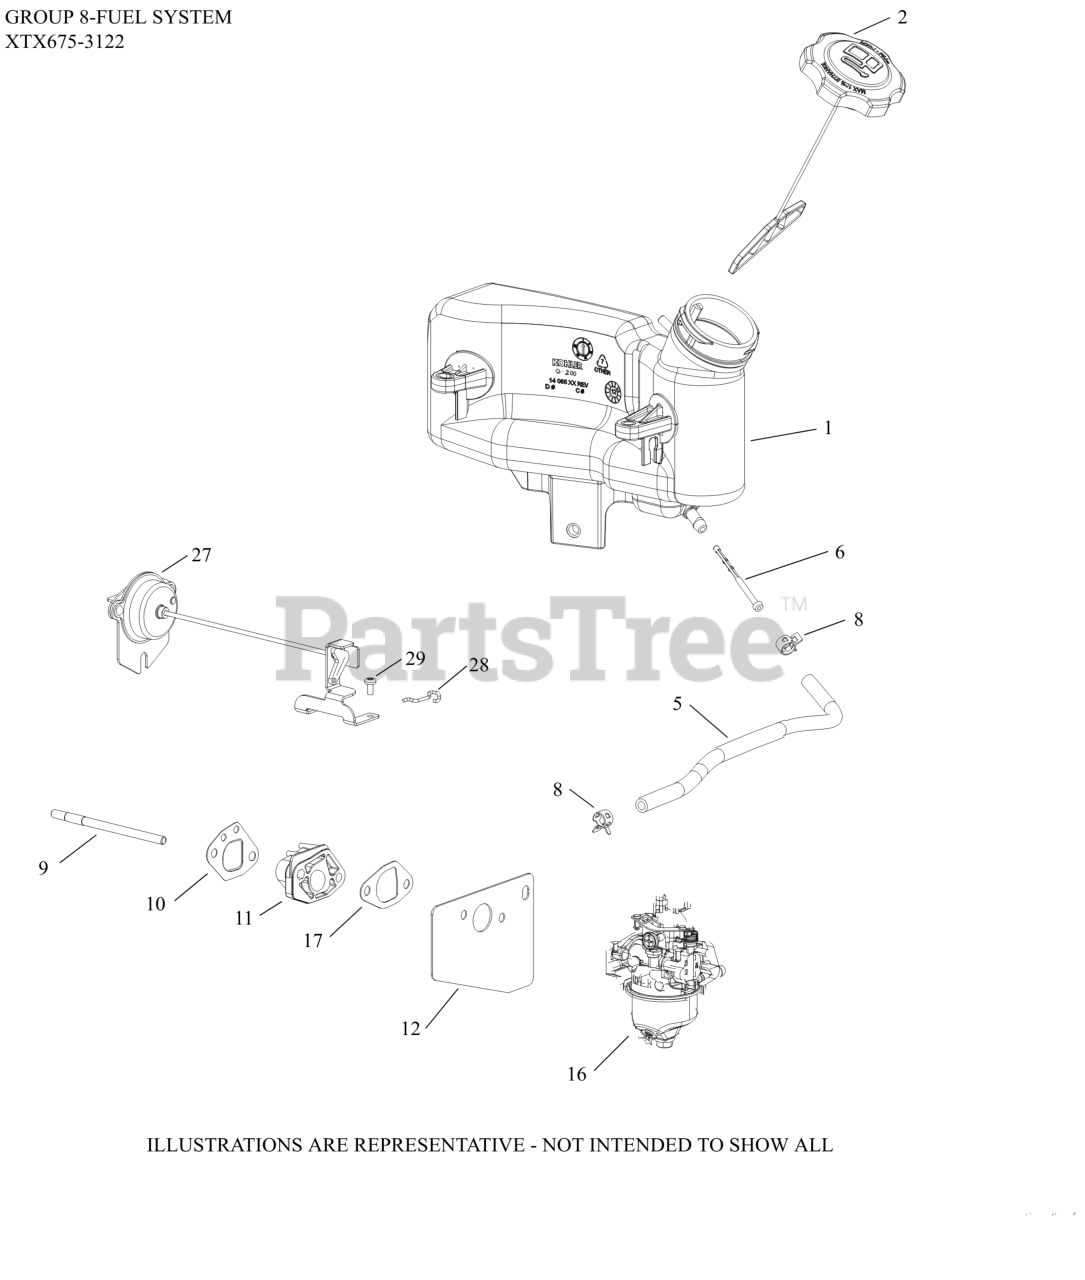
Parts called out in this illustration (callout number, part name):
1	TANK, FUEL
2	FUEL CAP ASSEMBLY
5	HOSE, FUEL LOW-PERMEATION (CKY)
6	FILTER, FUEL IN-NIPPLE
8	CLAMP, HOSE (NON-CALIF)(#1423710S)
9	STUD,M6X1.0X100.2MM
10	GASKET, SPACER - USE 14 041 24-S
11	SPACER, CARBURETOR
12	KIT, CARBURETOR HEAT SHIELD GASKET
16	KIT, CARBURETOR COMPLETE
17	KIT, INTAKE GASKET
27	ARM ASSEMBLY, AUTO CHOKE
28	LINKAGE, WIRE CHOKE
29	SCREW, M4 THRD FRMNG-(#25086439S)
NI	KIT, HIGH ALTITUDE (4,000-8000 FT)
NI	KIT, CARBURETOR REPAIR (HUAYI)
